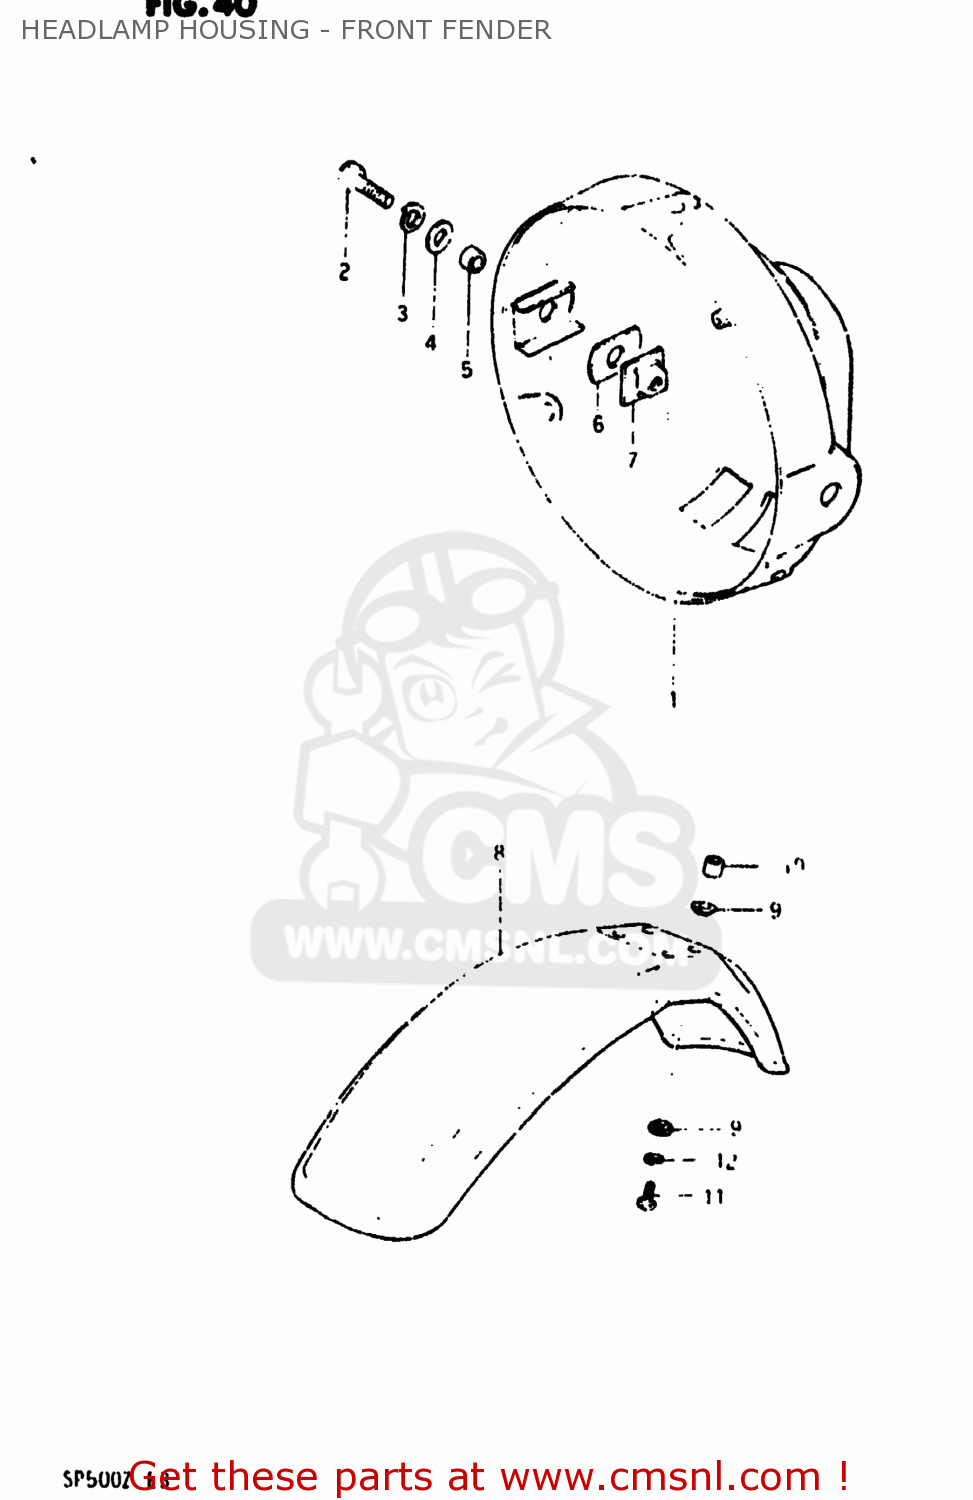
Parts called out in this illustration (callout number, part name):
1	HOUSING,HEADLAMP
2	BOLT
3	LOCK WASHER
4	WASHER
5	SPACER (8.8X12X7)
6	CUSHION
7	PLATE,HEADLAMP HOUSING
8	FENDER,FRONT
9	WASHER
10	SPACER (6.8X10X27.4)
11	BOLT
12	LOCK WASHER
